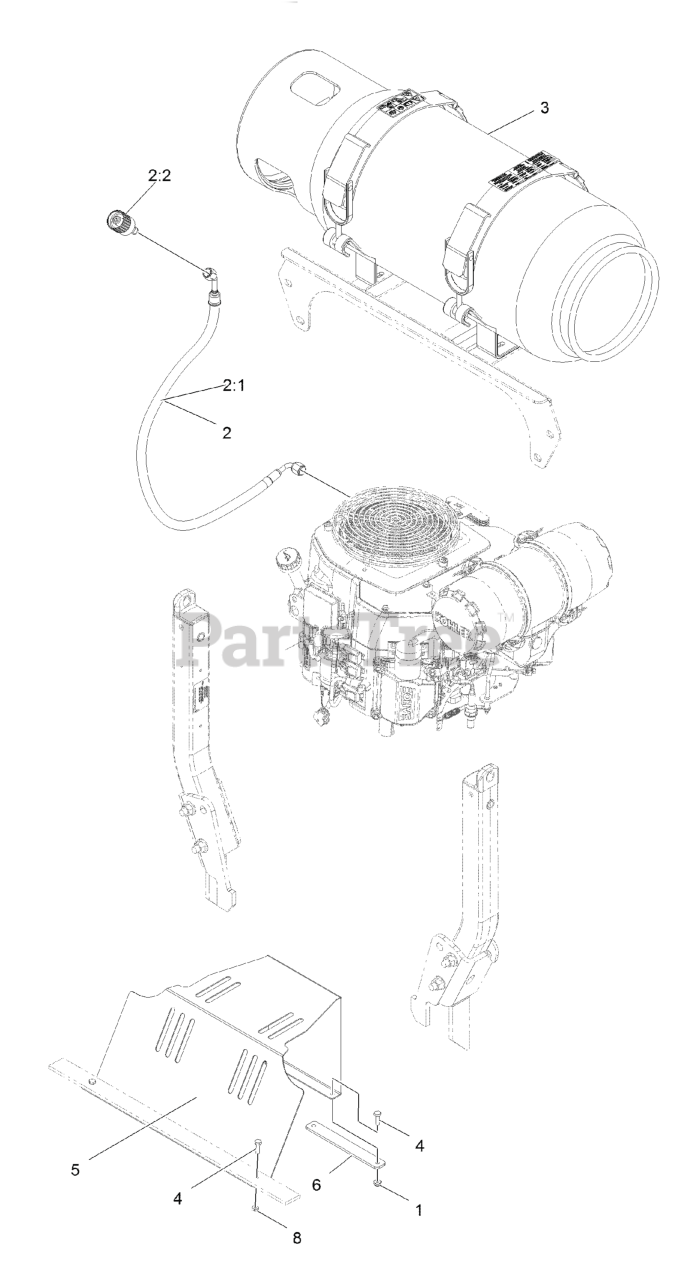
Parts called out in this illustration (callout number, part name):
2	LPG HOSE ASM
2:1	HOSE ASM, LPG
2:2	CONNECTOR-LP, STRAIGHT
3	TANK-LPG
4	SCREW-HH
5	SHEILD-FAN
8	NUT-JAM
